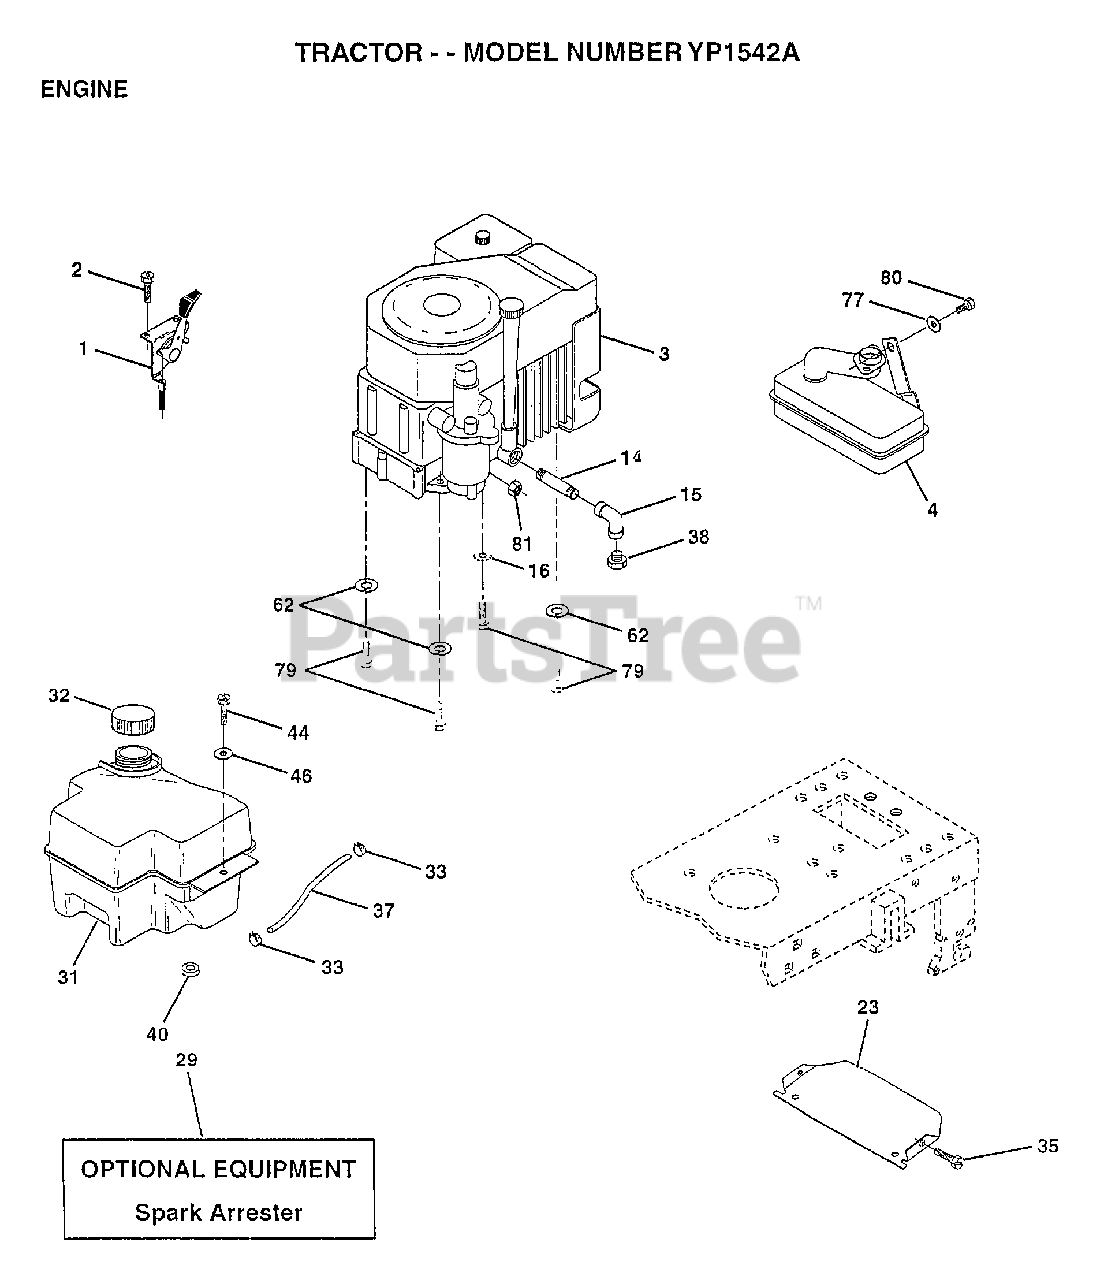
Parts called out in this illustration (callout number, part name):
1	CONTROL.THROTTLE/CHOKE
2	SCREW LT
3	ENGINE KOHLER
4	MUFFLER.LT.12.5
14	PIPE NIPPLE
15	ELBOW
16	LOCKWASHER.5/16.E
23	SHIELD-HEAT
32	CAP ASM FUEL
33	HOSE CLAMP
35	SCREW
37	LINE FUEL
44	SCREW HEX CRT
46	WASHER
62	LOCKWASHER
80	BOLT
81	NUT
